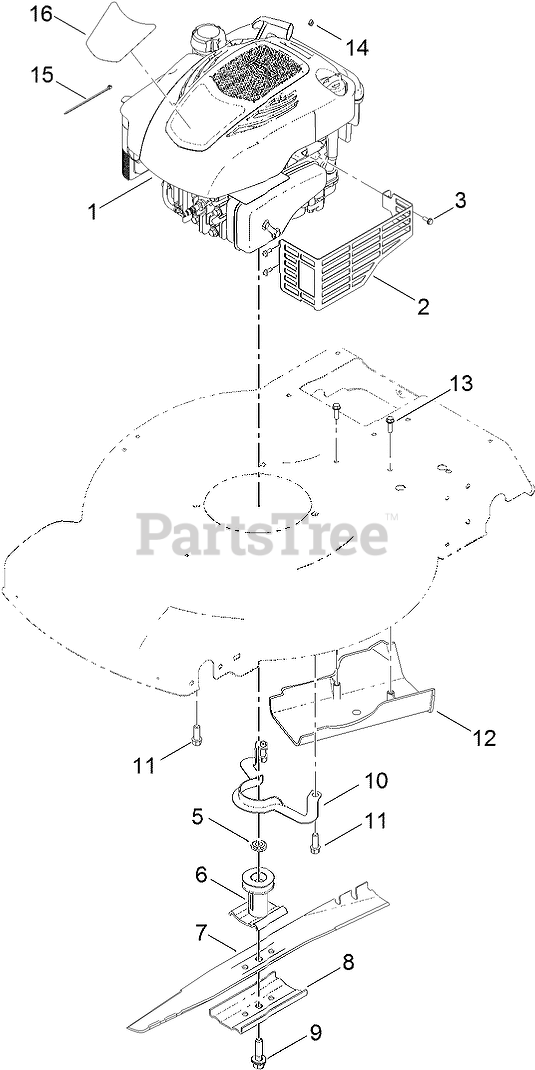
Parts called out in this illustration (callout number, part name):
2	SHIELD-MUFFLER
3	SCREW-TAPTITE
5	Spacer-Driver
6	DRIVER-BLADE
7	BLADE
8	Accelerator-Blade
9	BOLT-BLADE
10	Guide-Belt
11	SCREW-TAPTITE
12	COVER-BELT
13	SCREW-HWH
14	STOP-ROPE
15	TIE-CABLE, MOTOR
16	DECAL-SHROUD
